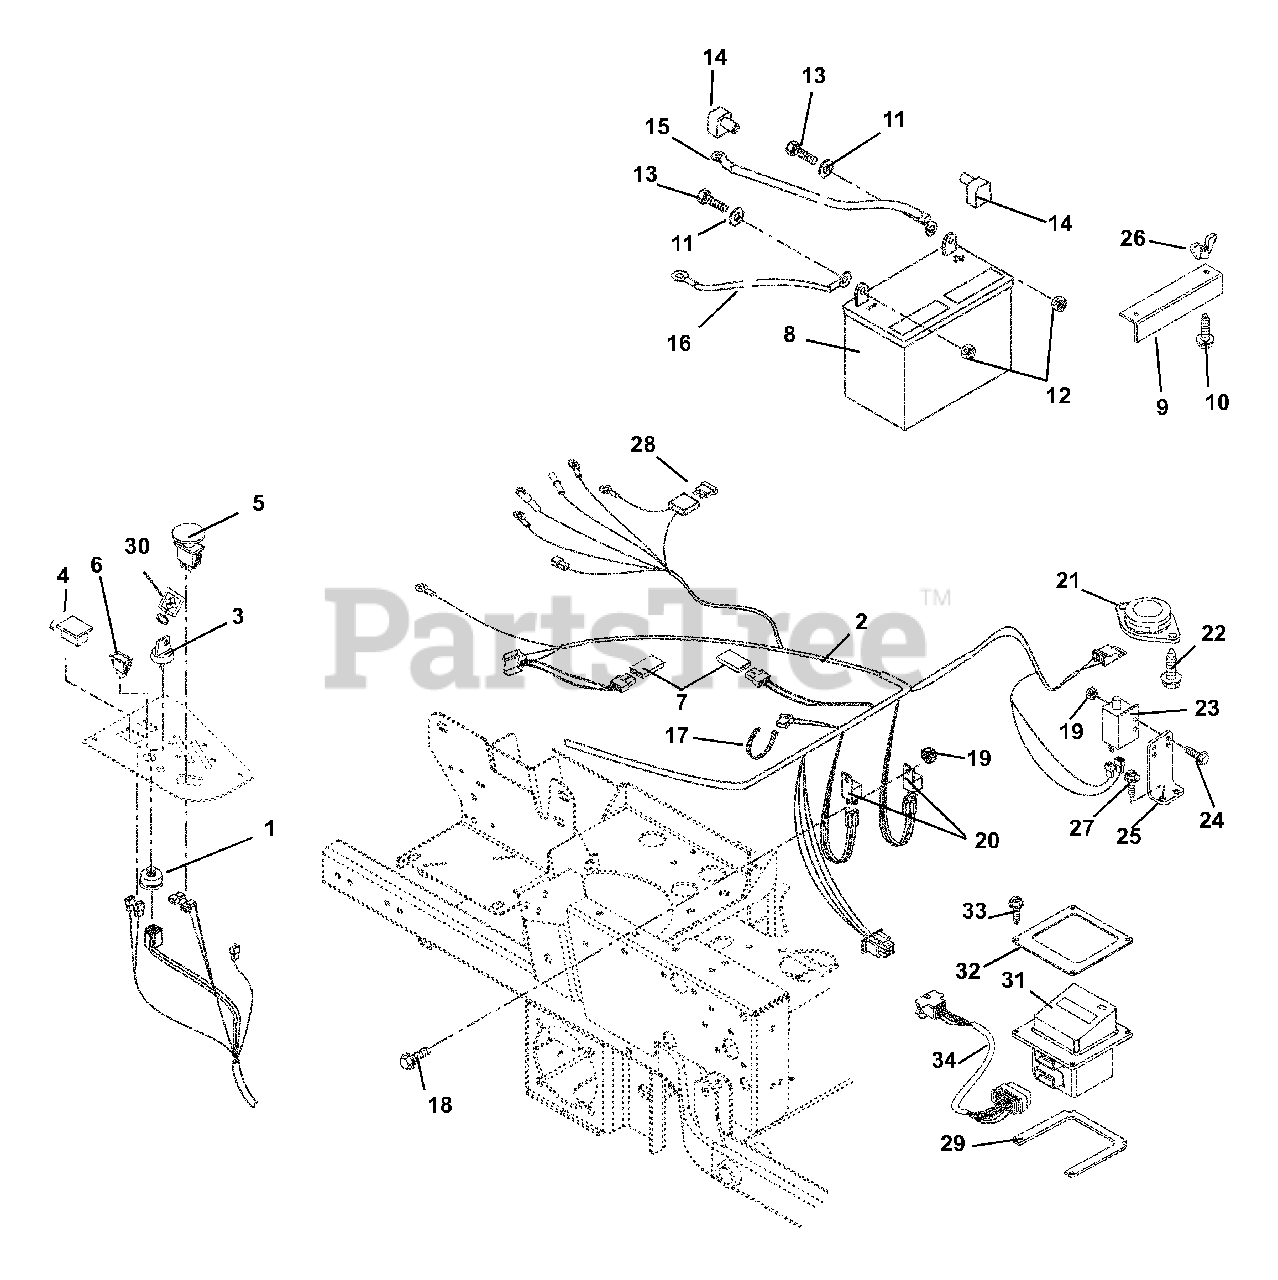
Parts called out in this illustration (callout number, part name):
1	Key Switch
2	Harness, Z-6 Pin (EYE-Q)
3	Key with Shield
5	Switch, Clutch With Retainer Ring
6	Light, Indicator
7	Diode, Connector Shell
9	Hold Down
10	Bolt, Round Head Square Neck .25-20 x 7.50
11	Washer, Flat Steel .281 x .620 x .065
12	Nut, Locking Top Flange .25-20
13	Bolt, Hex .25-20 x .75 Grade 5
14	Insulator
15	Cable, Positive, 26 inch
16	Cable, Negative Battery
17	Cable Tie
18	Screw, Machine 10-24 x .50 Hex Washer Head
19	Nut, Locking Nylon 10-24 With Insert
20	Relay
21	Seat Switch
22	Screw, Tapping 12-24 x .50 Hex Washer Head
23	Switch, Single Pole
24	Screw, Machine 10-24 x .75 Hex Washer Head
25	Mount, Brake Switch
26	Nut, Locking Wing .25-20
27	Screw, Tapping .25-20 x .50 Hex Washer Head
28	Fuse, 30 Amp
29	Spacer, Enclosure Mounting (Bottom)
30	Key Chain
31	Assembly, Eye-Q
32	Plate, Eye-Q Stiffener (Top)
33	Screw, Machine 10-24 x 1.0 Slotted Pan Black
34	Harness, Eye-Q
